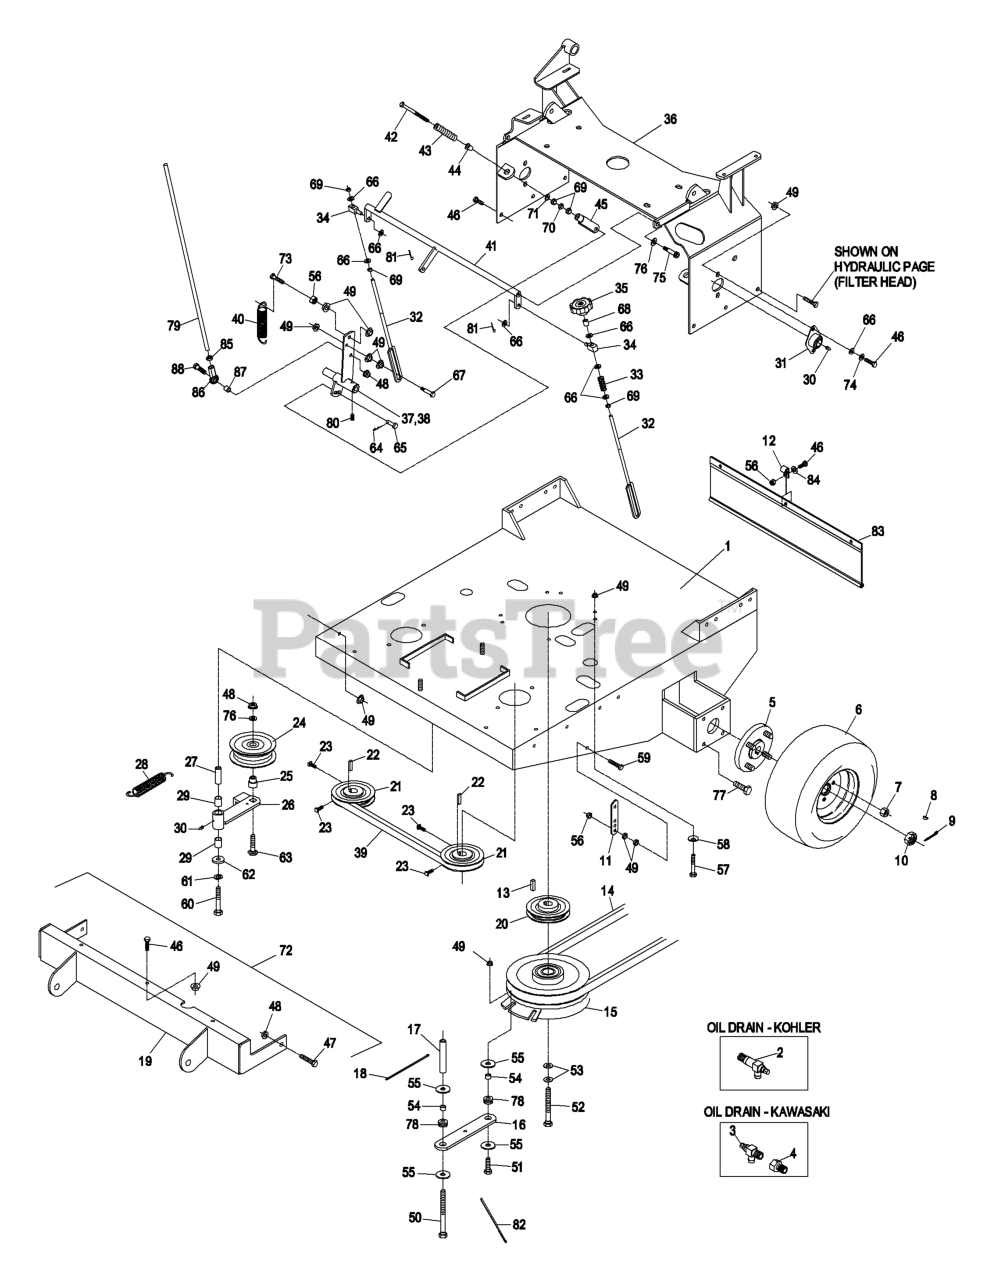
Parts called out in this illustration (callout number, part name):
2	VALVE-DRAIN, OIL
3	VALVE-DRAIN, OIL
4	ADAPTER
6	ASM, DRIVE TIRE
7	NUT-LUG
8	KEY-WOODRUFF
9	PIN-COTTER
10	NUT-HEX, SLOTTED
11	TAB-SPRING, EXTENSION
12	CLIP-LOOM
14	BELT,B 83.65
15	CLUTCH ASM
16	STRAP-CLUTCH, BRAKE
18	TIE-CABLE
19	WLD,SULKY HITCH
20	PULLEY
21	SHEAVE ASM
23	SCREW-SET
25	BUSHING-IDLER
26	IDLER ARM ASM
27	BUSHING
28	SPRING-EXTENSION
29	SLEEVE-BEARING
30	FITTING-GREASE
31	BEARING-FLANGE, SIDE
32	LINK,SPEED CONTROL
33	SPRING-COMPRESSION
35	KNOB-TRACKING
37	WLD,LH CONTROL ARM
40	SPRING-EXTENSION
41	WLD,CRANK SPEED CNTRL
42	BOLT-RETURN, NEUTRAL
43	SPRING,COMPRESSION (NEUT)
44	BUSHING-FLANGED
45	YOKE-ADJUSTABLE
46	SCREW-HH
47	SCREW-HH
48	NUT-HHF, WHIZ
50	SCREW-HH
51	SCREW-HH
52	SCREW-HH
53	WASHER-SPRING
56	NUT-LOCK, NI
57	SCREW-HH
58	WASHER-SPRING
59	BOLT-TAP, HH
60	BOLT-CARR
61	WASHER-LOCK
63	SCREW-CARR
64	PIN-COTTER
65	PIN-CLEVIS
66	WASHER-PLAIN
67	SCREW-HH
69	NUT-HEX
70	NUT-JAM
71	WASHER-FLAT
72	Hitch Kit, Sulky
73	SCREW-HH
74	WASHER-LOCK
75	SCREW-HSH
76	WASHER-FLAT
77	SCREW-HHF
78	GROMMET
79	LINK,DRIVE (PLTD)
80	SCREW-SET
81	PIN-COTTER
82	TIE-PLASTIC
83	SHIELD,DRAG
84	WASHER-FLAT
85	NUT-HEX JAM, LH
86	JOINT-BALL END, LH
87	TUBE,PUMP LINK SPACER
88	SCREW-HH
